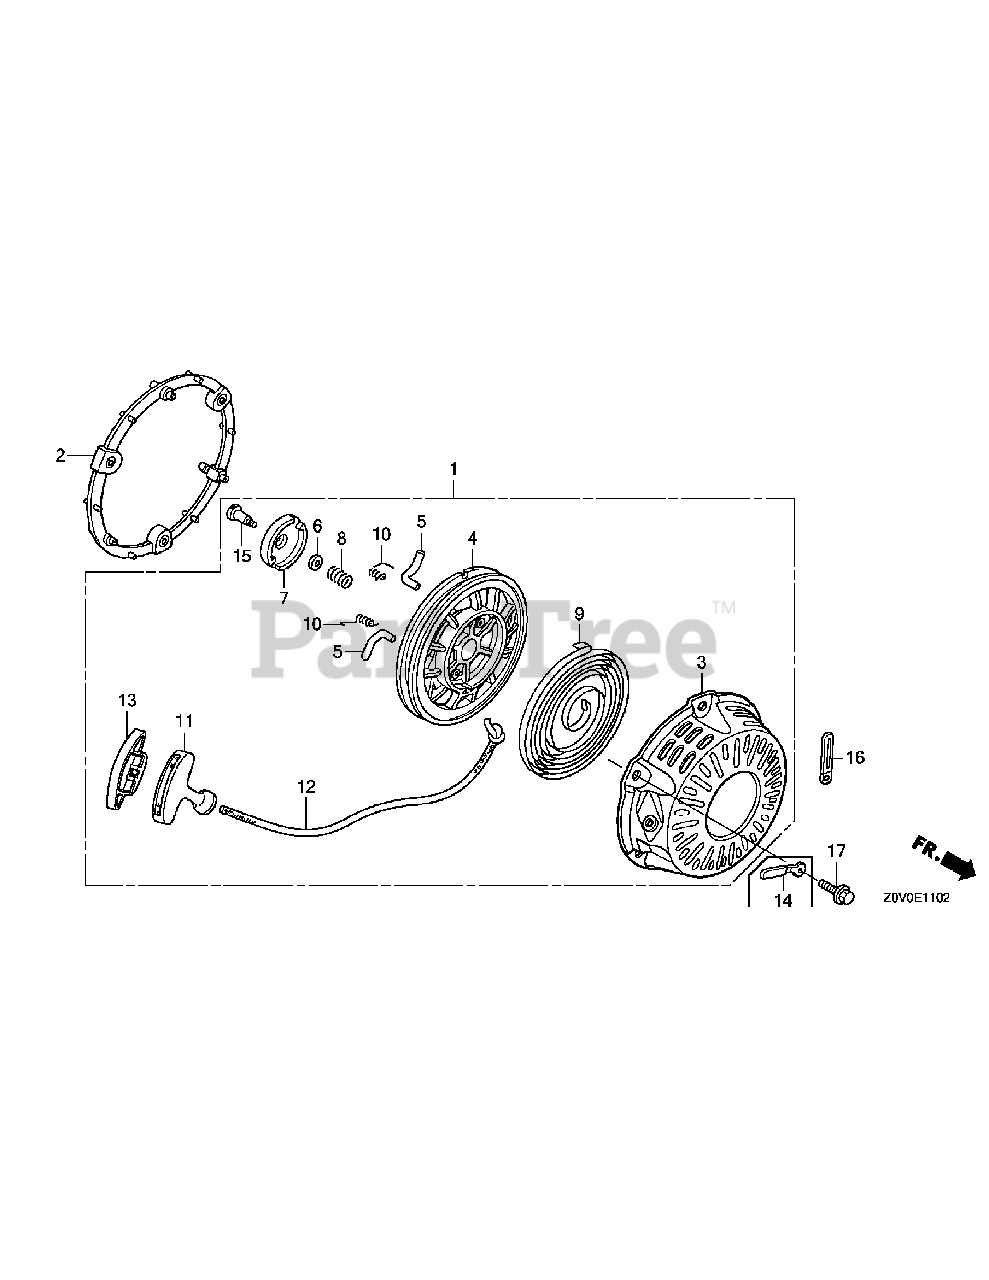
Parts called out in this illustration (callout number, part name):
1	Starter Assy., Recoil
2	Spacer, Recoil Starter
3	Case Comp., Recoil Starter
4	Reel, Recoil Starter
5	Ratchet, Starter
6	Plate, Friction
7	Guide, Ratchet
8	Spring, Friction
9	Spring, Recoil Starter
10	Spring, Return
11	Knob, Recoil Starter
12	Rope, Recoil Starter
13	Knob, Reinforcement
14	Clip, Sub Cord
15	Screw, Setting
16	Clip, Wire
17	Bolt, Flange, 6X18
